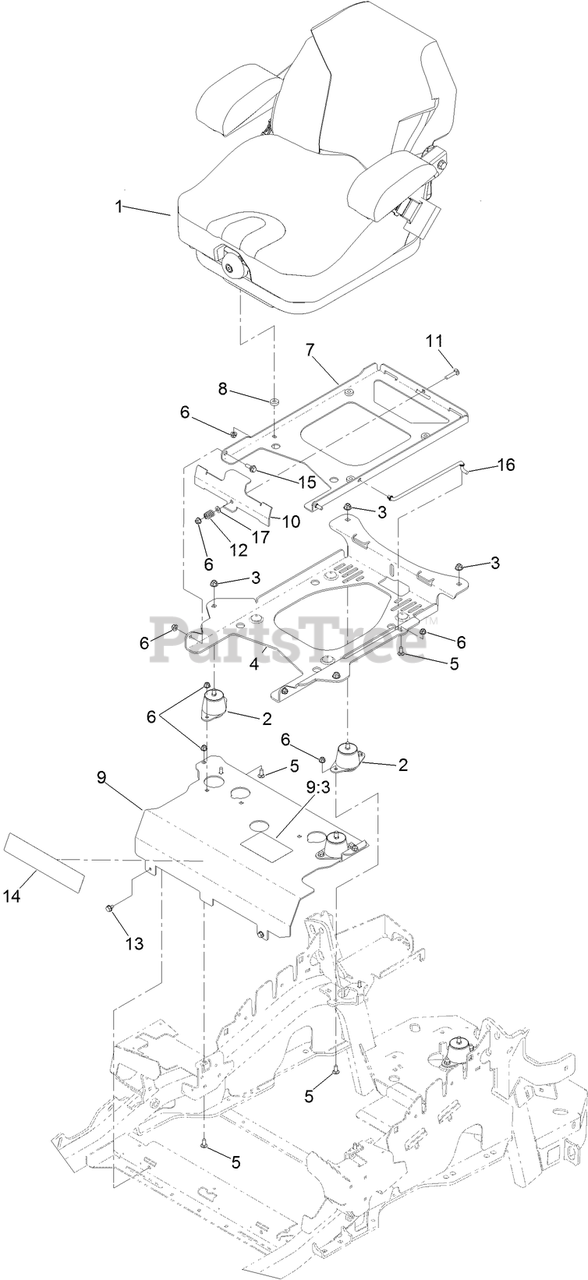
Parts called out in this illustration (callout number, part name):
1	SUSPENSION SEAT ASM
2	ISOLATOR-SEAT
3	NUT-HF, NI
4	PLATE-TILT, SEAT SUPPORT
5	SCREW-CARR
6	NUT-HF, NI
7	PLATE-FRAME, SEAT
8	SPACER-PIN, MOUNTING
9	SEAT MOUNT ASM
9:3	DECAL-SERVICE AID
10	PLATE-LATCH, SEAT
11	BOLT-CARR
12	SPRING-COMPRESSION
13	SCREW
14	DECAL
15	SCREW-SHOULDER
16	ROD-PROP
17	WASHER-PLAIN
